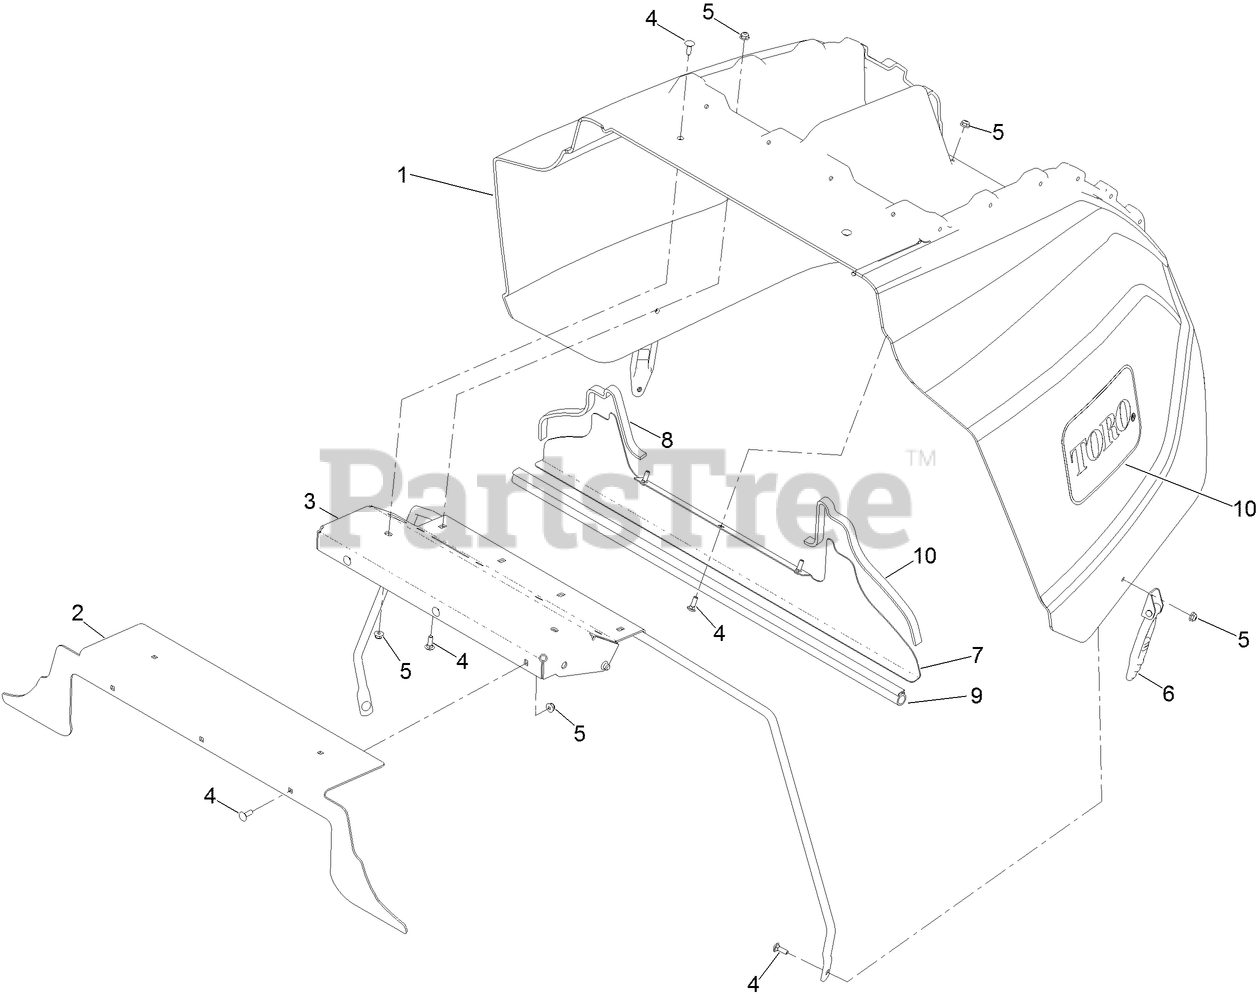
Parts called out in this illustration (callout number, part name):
2	BLOCK OFF-HOOD
3	SUPPORT-HOOD
4	BOLT-CARR
5	NUT-HF
6	LATCH-RUBBER
7	PLATE-SEAL
8	SEAL-FOAM
9	SEAL-BULB
10	DECAL
